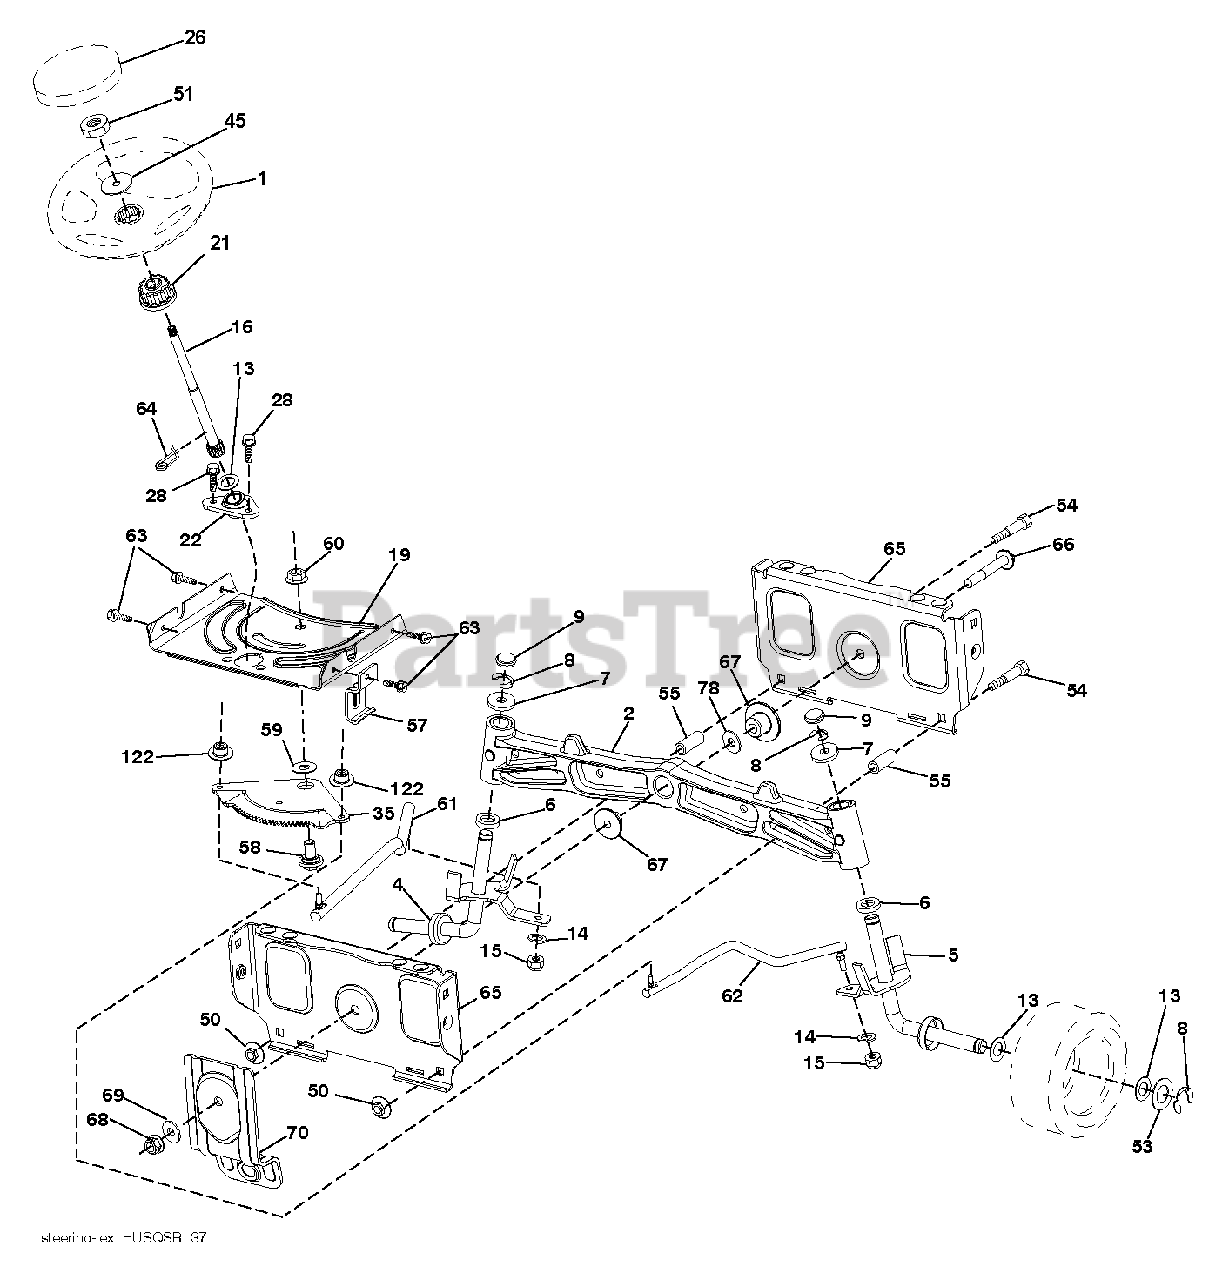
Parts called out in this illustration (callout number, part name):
1	WHEEL.STEER.HUSQ.SR.498.OVMLD
2	AXLE.CAST.IRON
4	SPINDLE.WELDED.LH.16"TEX
5	SPINDLE.WELDED.RH.16"TEX
6	THRUST WASHER
9	CAP.SPINDLE.BLACK
14	WASHER, LOCK 3/8
15	NUT CROWNLOCK 3/8-24
16	SHAFT, STEERING
19	PLATE.STEER.DDL.NLT/NG
21	ADAPTER, WHEEL STNG..
22	STEERING.SUPT.LOWER.
26	INSERT.CAP.WHL.STRG.HUSQ.PREM
28	SCREW, 3/8-16X3/4
35	GEAR.SECTOR.PLATE.DDL.
45	WASHER 9/16"ID, 2 3/8"OD
50	NUT LOCK FLG 3/8-16 UNC
51	NUT.HEX.1/2-20
53	WASHER.HARDENED
55	SPACER.BRACE.AXLE
57	BRKT.UPSTOP.GT/LT.TEX
58	BOLT.SHOULDER.SECTOR.P
59	WASHER.THURST.SECTOR.S
60	NUT FLANGE LOCK 5/8-11
61	DRAGLINK.LH.BALLSTUD.D
62	DRAGLINK.RH.BALLSTUD.D
63	SCREW
64	RETAINER.CLIP.SPRING.S
65	BRACE.AXLE.FRONT.NLT/N
66	BOLT HEX FGHD 7/16-14 X 3 SERR
67	BUSHING.PM.FRONT AXLE
68	NUT.LOCK.FLANGE.7/16
69	WASHER.1.5X.505X.118
70	BRKT.DECK.SUSPENSION.F
78	THRUST WASHER
122	CAP.GEAR.SECTOR.TEX
